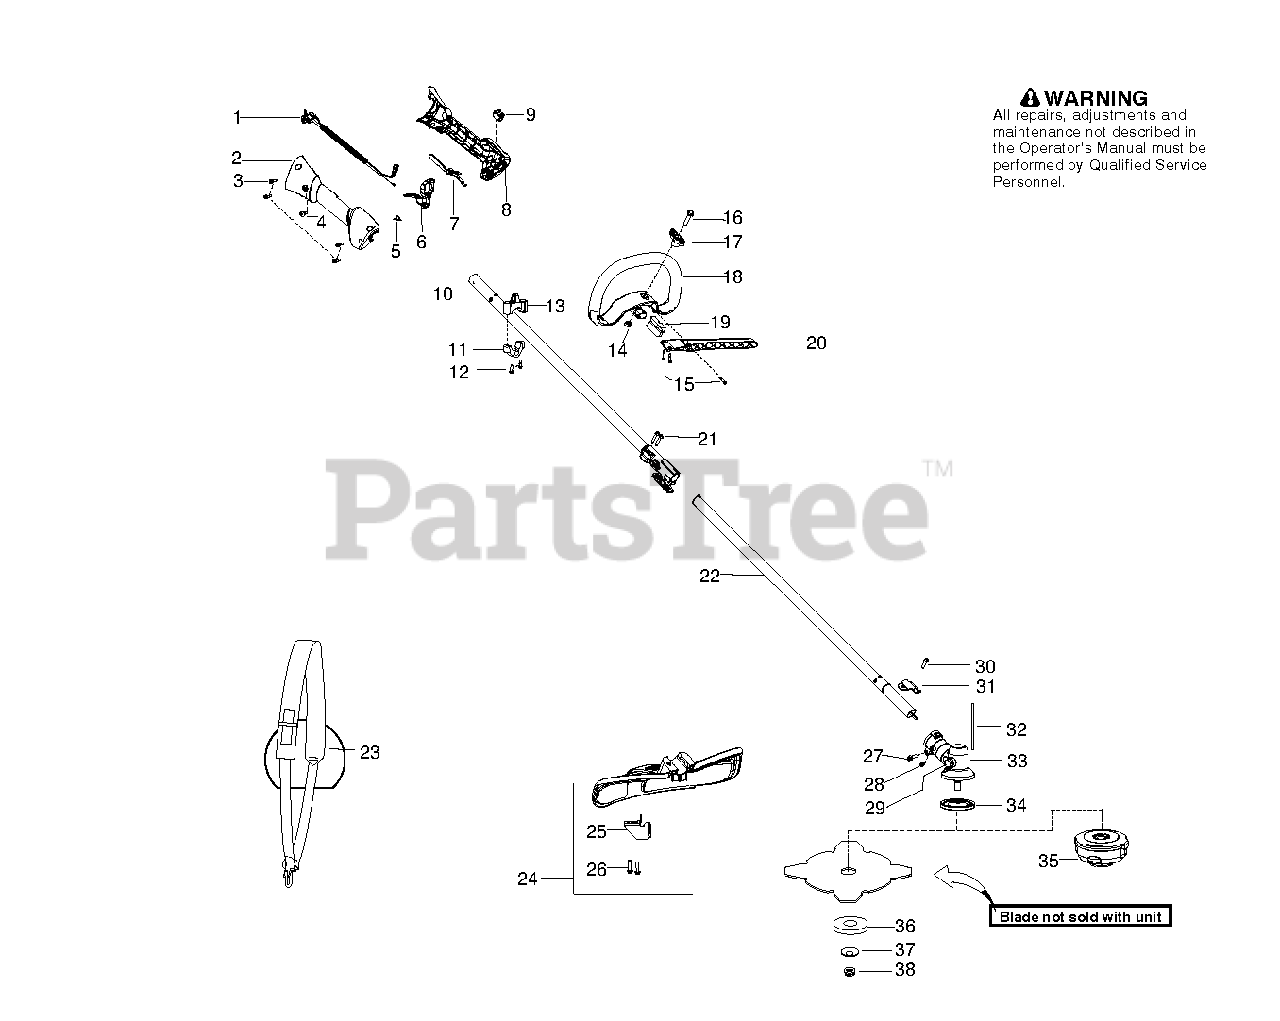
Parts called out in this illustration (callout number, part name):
1	ASSY CABLE / WIRE HARNESS
2	HOUSING RIGHT
3	SCREW M4 X 1.75 PT 16MM
4	SCREW-10-16 X 1/2, TYPE 2
5	SPRING TRIGGER
6	TRIGGER
7	THROTTLE LOCKOUT
8	HOUSING THROTTLE LH
9	SWITCH
10	KIT DRIVESHAFT UPPER
11	CLAMP HARNESS LOWER
13	CLAMP HARNESS UPPER
15	SCREW IHSCFTO
16	SCREW M6X50
20	HANDLE
22	KIT LOWER SHAFT
23	SHOULDER STRAP WITH SIGN
24	KIT SHIELD
25	LINE CUTTER
27	SCREW - CARB. ADAPTOR
29	PLUG
30	SCREW 1/4-20 X 7/8 (TAP
31	BRACKET SHIELD STRAIGHT SHAFT
32	LOCKING PIN
33	ASSY GEARBOX
34	DRIVE DISC
35	T25 TRIM HEAD 10MM LH
36	SUPPORTING CUP
37	SUPPORT FLANGE
38	GEARHEAD NUT - BRUSHCUTTER
